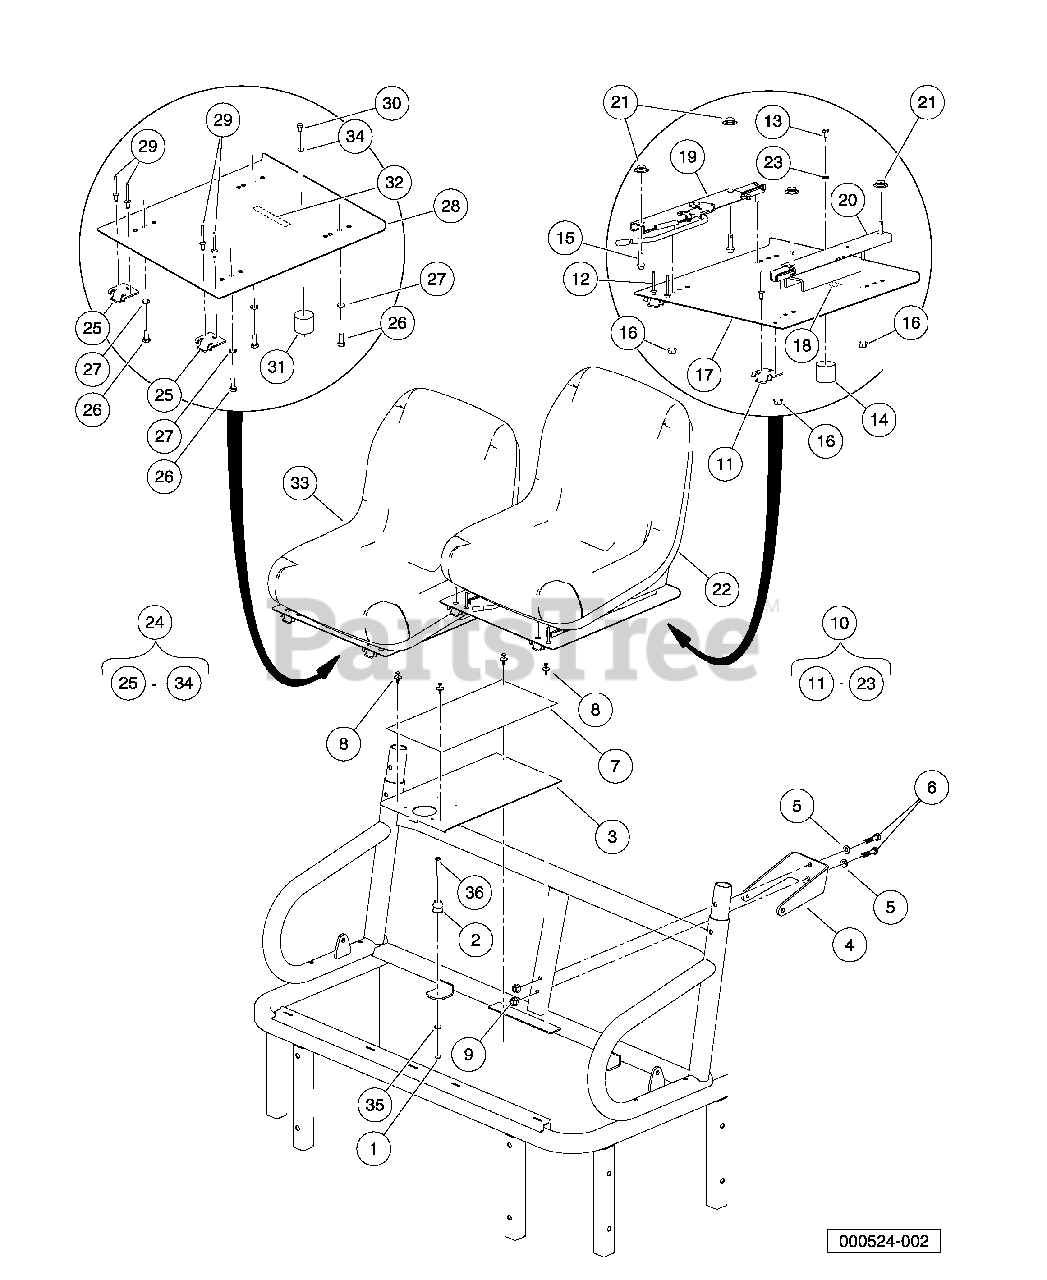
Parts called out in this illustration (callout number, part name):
1	Locknut, M6-1.00 Nylon Insert
2	Seat Holder Base
3	Pan, Center, Closeout
4	Bracket, Seatbelt, Bolt-On
5	Washer, Hard, M10, Zn-Ni/Blk
6	Bolt, M10 X 45, Zn-Ni (Black)
7	Cover, Center Console
8	Rivet, Removable, Tuflok 1/4"
9	Nut, Flanged, M10 x 1.5, Black
10	Asm, Bracket Seat, Adj, Blk
11	Hinge Plate
12	Rivet, 1/4 X .438 Blind
13	Screw, 6m-1.00 X 10mm Hex Head
14	Seat Holder Cup
15	Bolt, Flange Head, M8 X 30.0
16	Nut,m8,all Metal Lock
17	Pan, Seat, Driver Asm
18	Decal, Hot Surface Warning
19	Adjuster, Forward/Aft
20	Adjuster, Slider
21	Washer, Bell
22	Seat, Bucket, Black
23	Lockwasher, 1/4 Helical Split
24	Asm, Bracket Seat, Passenger, Blk
25	Hinge Plate
26	Screw, M8-125 X 22 Hex-Head
27	Lockwasher, 8mm Split
28	Pan, Seat, Passenger
29	Rivet, 1/4 X .438 Blind
30	Screw, 6m-1.00 X 10mm Hex Head
31	Seat Holder Cup
32	Decal, Hot Surface Warning
33	Seat, Bucket, Black
34	Lockwasher, 1/4 Helical Split
35	Washer, 1/4 Type A Narrow Flat
36	Bolt, M6 X 1 X 45
